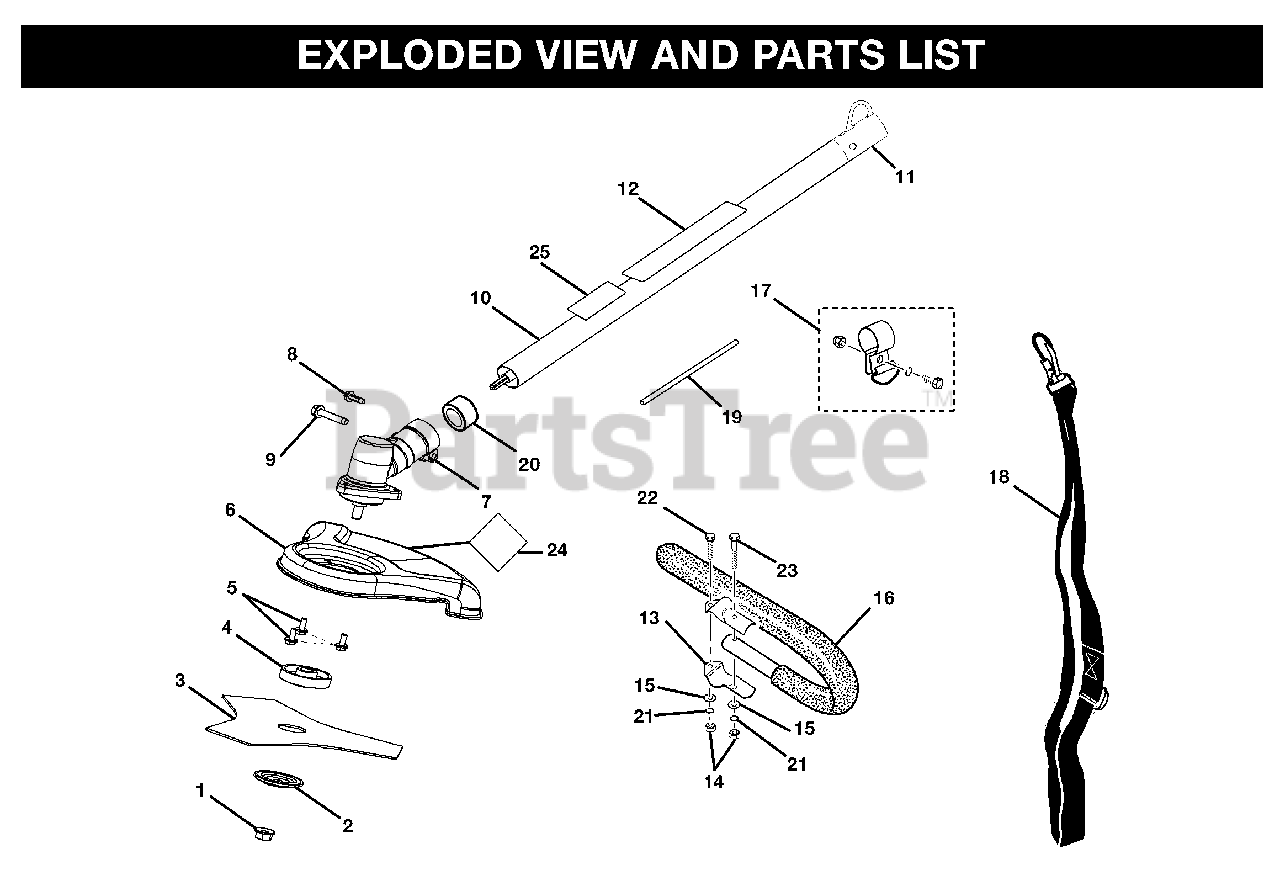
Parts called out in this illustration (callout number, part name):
1	Blade Nut, Left-handed Threads (M8)
2	Cupped Washer
3	Blade (Tri-Arc®)
4	Flanged Washer
5	Screw (10-24 x 1/2 in. Hex Head w/Dish Washer)
6	Brushcutter Guard
7	Gear Head Assembly
8	Screw (10-24 x 5/8 in.)
9	Screw (1/4 in.-20 x 1-1/4 in., Hex Head)
10	Boom Assembly
11	Hanger Cap
12	Warning Label
13	Handle Bar Clamp
14	Hex Nut (1/4 in.-20)
16	J-Handle and Grip
17	Strap Hanger
18	Shoulder Harness Assembly
19	Head Locking Tool
21	Lock Washer (1/4 in.)
22	Bolt (1/4 in.-20 x 1 in.)
23	Bolt (1/4 in.-20 x 1-1/2 in.)
24	Logo Label
25	Logo Label
